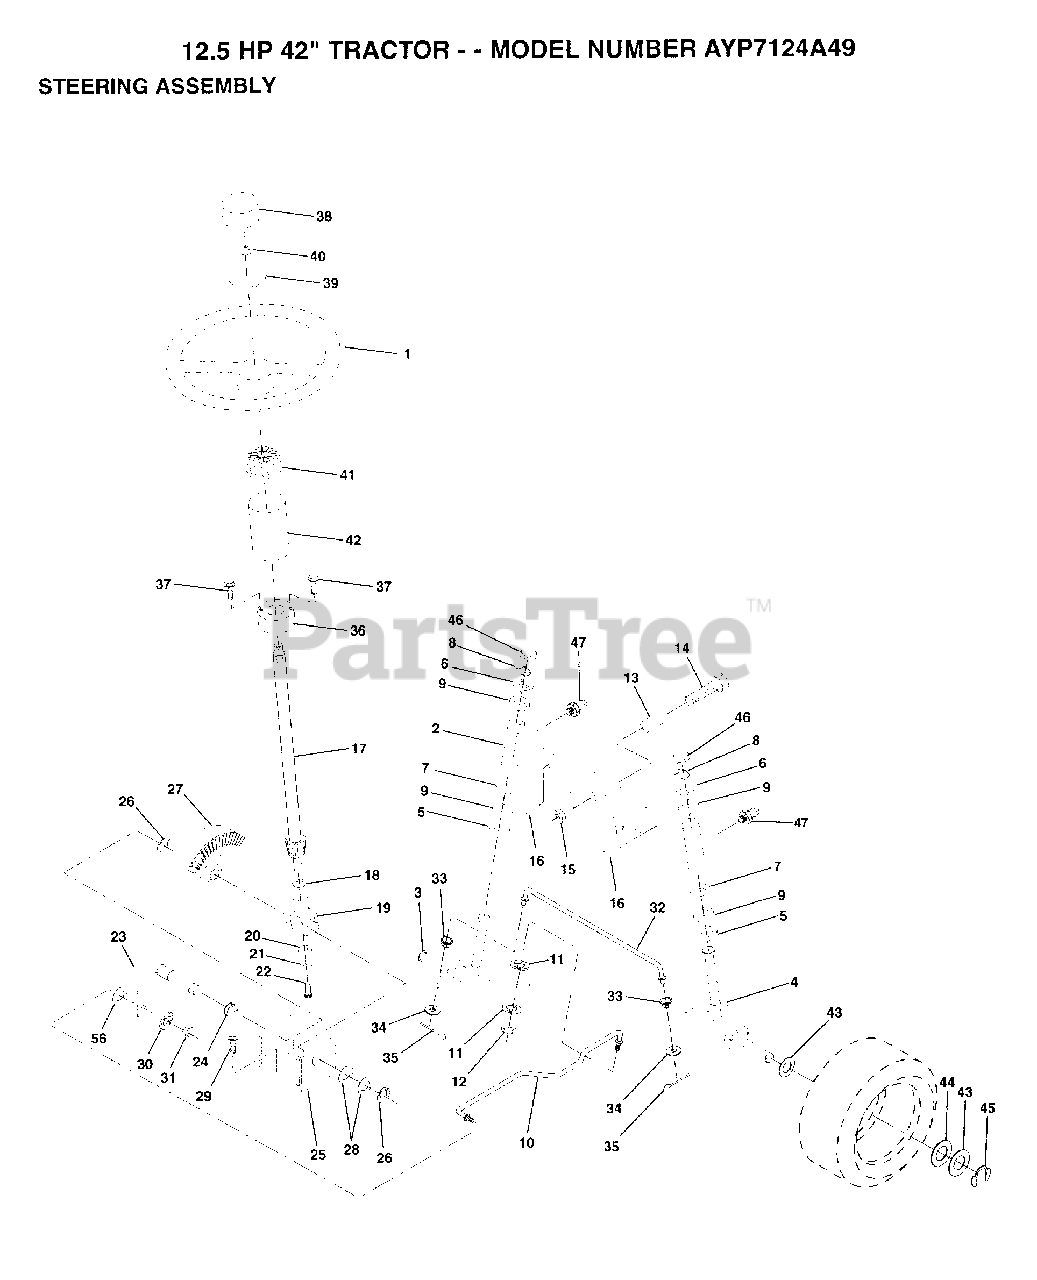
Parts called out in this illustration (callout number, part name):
3	SPINDLE LH
4	SPINDLE RH
5	WASHER .T
6	WASHER
7	WASHER
8	RING
9	COL. SRTG. BEAR.
11	LOCKWASHER
13	BEARING
14	BOLT HEX 5/8-11
15	"NUT-LOC,FLANGE LT"
16	AXLE PIN
17	SHAFT ASM
18	THRUST WASHER
19	SUPPORT.SHAFT
21	LOCKWASHER
22	"SCREW,SPECIAL"
24	NYLINER T
25	"BRKT,STEERING"
26	RING
27	GEAR SECTOR
28	WASHER .T
29	SCREW
30	LOCKWASHER
32	TIE ROD
33	BUSHING.DRAGLINK
34	WASHER
35	COTTER PIN
38	ST WHL INSERT CAP
39	WASHER T
40	GRIPCO NUT
41	ADAPTER-WHEEL LT
42	"TUBE, STR SHAFT"
43	WASHER
44	WASHER
45	RING
46	CAP
47	ZERK M
56	WASHER
